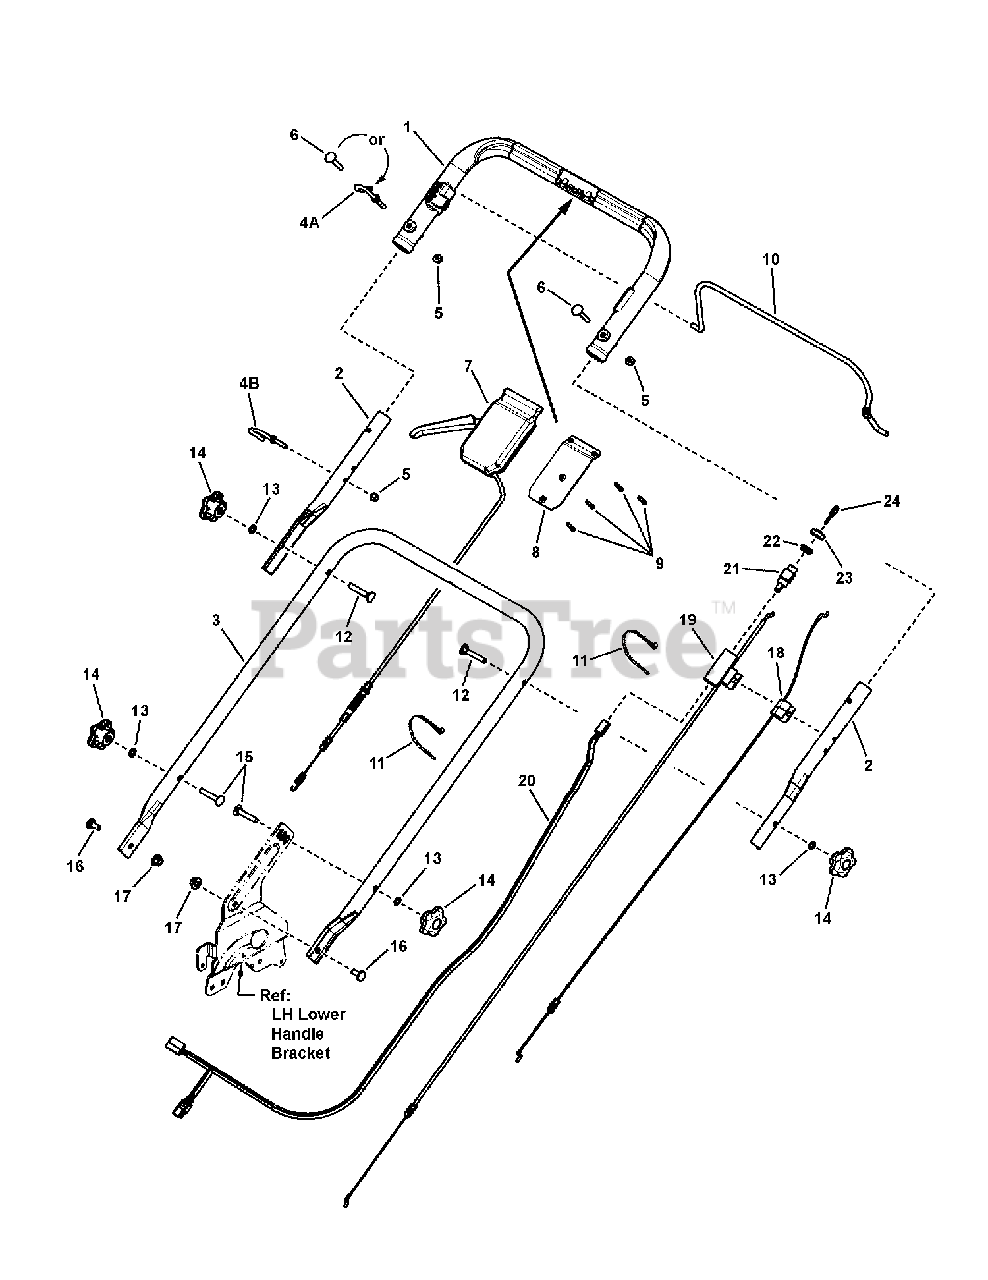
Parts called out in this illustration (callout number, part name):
1	HANDLE, Upper, Plastic, WBM
2	HANDLE, Connecting, 21" / 22" WBM
3	HANDLE, Lower, 1", WBM
4A	GUIDE, Rope (1/4-20 threads)
4B	GUIDE, Rope (1/4-20 threads)
5	NUT, 1/4-20 Hex Flange, Nyloc,YZ
6	BOLT, 1/4-20 x 1-3/4 Round Head Square Neck, GR 2
7	ASSY, Control Head, 22" WBM Variable Speed Rear Wheel Drive
8	PLATE, Control Panel, Plastic Handle
9	SCREW, Pan Head Thread Rolling
10	BAIL, Plastic Handle, WBM
11	WIRE TIE, 11"
12	BOLT, 5/16-18 x 2 Curved Head Square Neck, GR 2
13	WASHER, 5/16 Internal Tooth Lock
14	KNOB, Handle, 5-Prong (5/16-18 internal threads)
15	BOLT, 5/16-18 x 1-3/4" Round Head Square Neck Carriage
16	BOLT, 5/16-18 x 3/4" Round Head Short Square Neck Carriage, GR 5
17	NUT, 5/16-18 Large Flange Center lock
18	CABLE, Bail, 22" Walk-Behind Mower
19	* CABLE, Bail, 21" Walk-Behind Mower, Electric Start
20	WIRING HARNESS, ES
21	SWITCH, Electric Start, Start/Run
22	NUT, 5/8-32, ES
23	CAP, ES
24	KEY (Pair)
